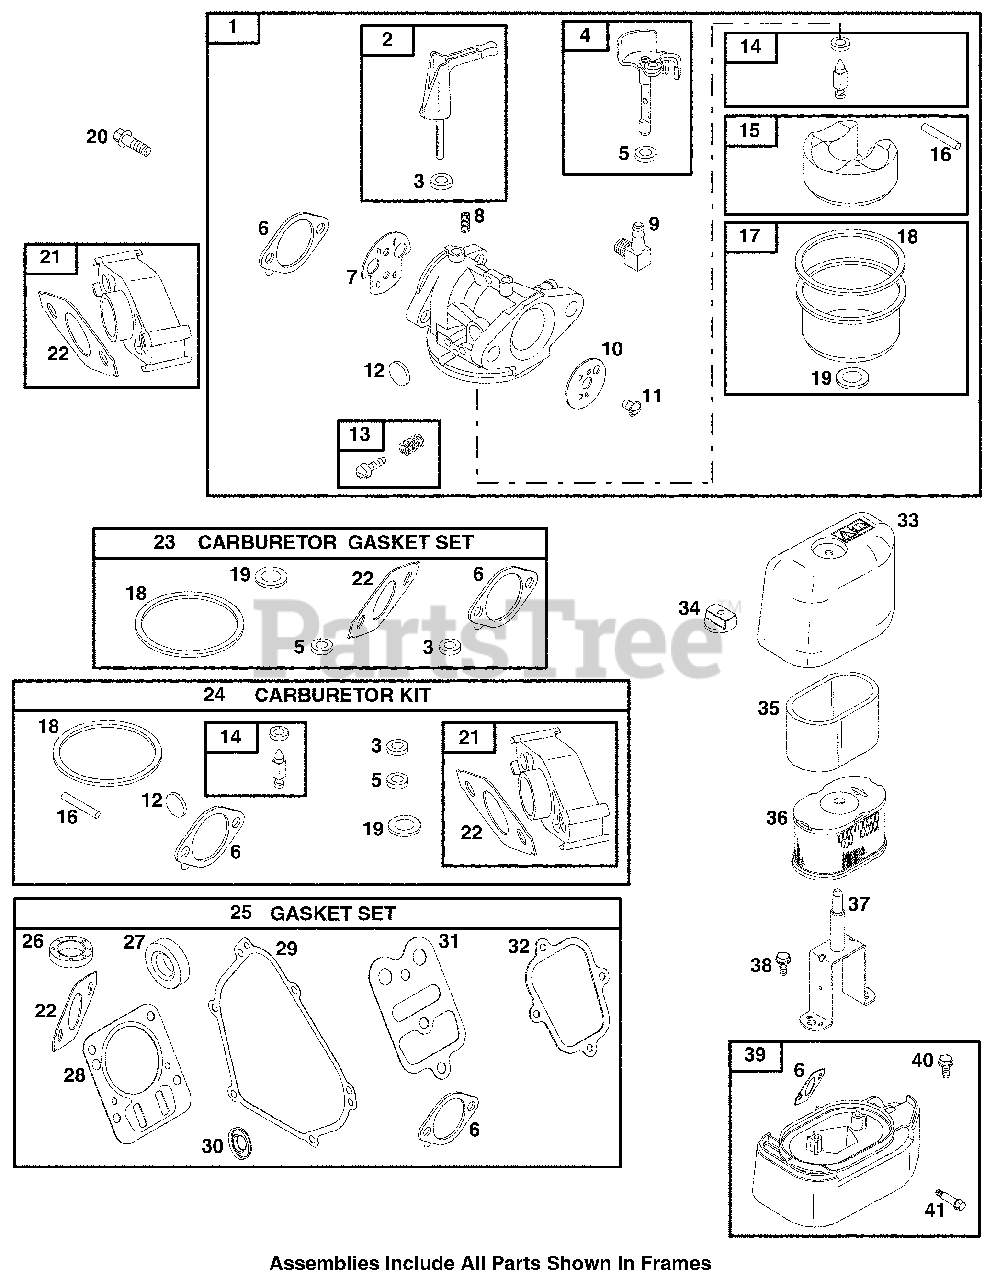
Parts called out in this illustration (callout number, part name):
1	Carburetor
2	Shaft-Choke
3	Washer
4	Shaft-Throttle
5	Washer
6	Gasket-Air Cleaner
7	Valve-Choke
8	Spring-Detent (Choke)
9	Connector-Hose
10	Valve-Throttle
11	Screw
12	Plug-Welch
13	Kit-Idle Speed
14	Valve-Needle
15	Float-Carburetor
16	Pin-Float Hinge
17	Bowl-Float
18	Gasket-Float Bowl
19	Washer-Seal
20	Screw
21	Spacer-Carburetor
22	Gasket-Intake
23	Gasket Set-Carburetor
24	Carburetor Kit
25	Gasket Set
26	Seal-Oil
28	Cylinder Head Gasket
29	Gasket-Crankcase
30	Seal-Valve
31	Gasket-Plate
32	Gasket-Rocker Cover
33	Cover-Air Cleaner
34	Knob-Air Cleaner
35	Filter-Air (Pre-Filter)
36	Filter A/C Cartridge
37	Air Cleaner Bracket
38	Screw
39	Base-Air Cleaner
40	Screw
41	Screw
